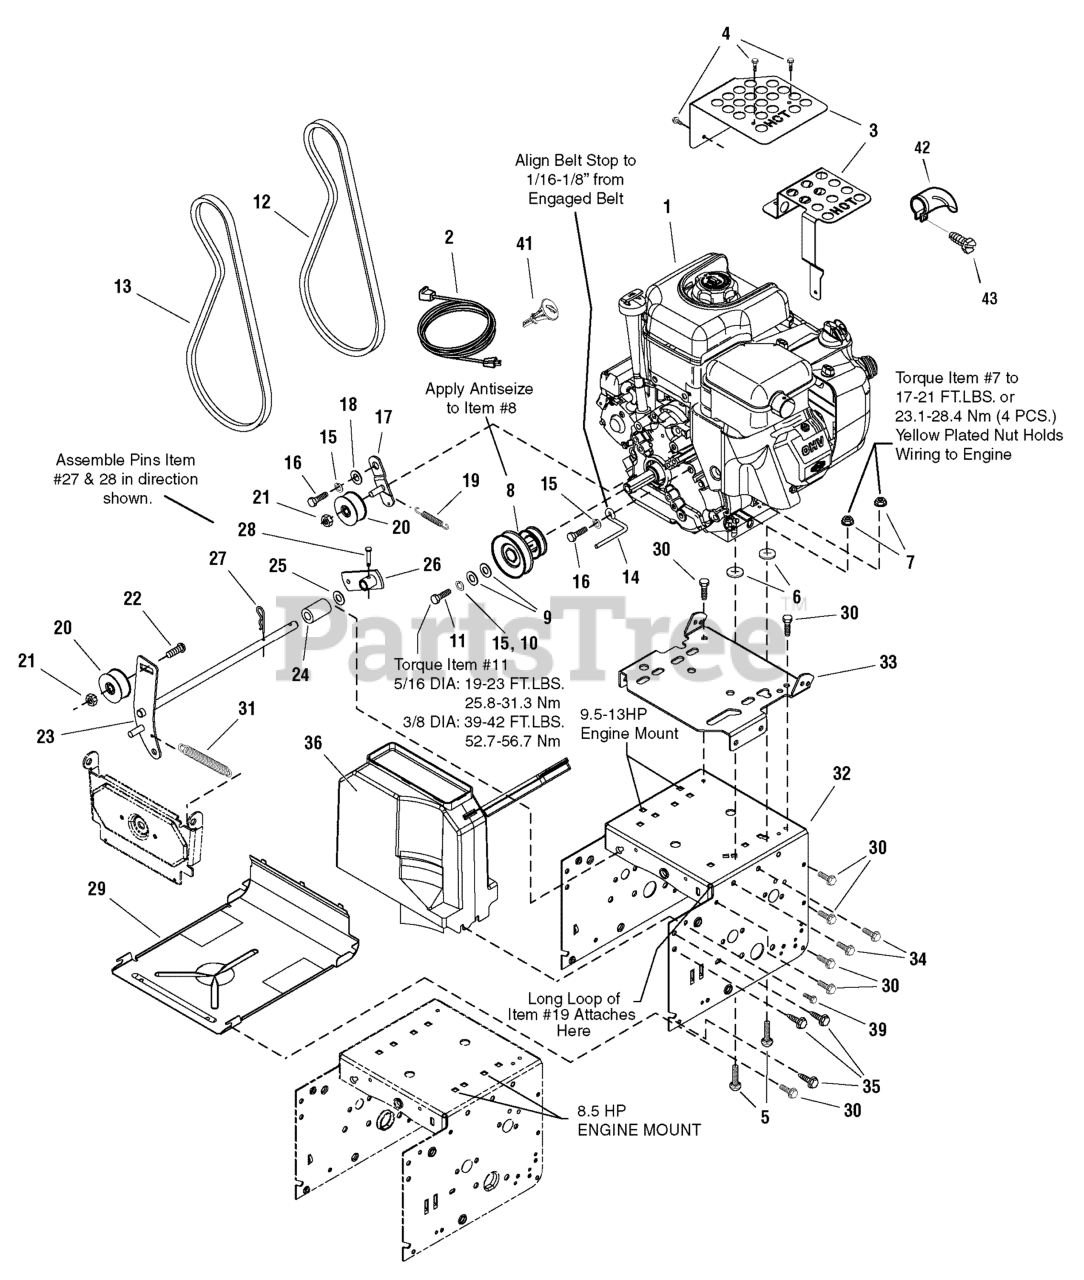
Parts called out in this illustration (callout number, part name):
1	ENGINE, 8.5HP B&S Powerbuilt *
1	ENGINE, 9.5HP B&S Powerbuilt *
2	CORD, Electric Start
3	GUARD, Muffler
4	SCREW, Hex Washer Head Taptite
5	CARRIAGE BOLT
6	NUT, Speed
7	NUT, Hex Flange, 5/16-18 Whiz Lock Small
8	PULLEY, Engine
9	WASHER, 3-5/16
9	WASHER, 3/8
10	LOCKWASHER, Spring 3/8
11	CAPSCREW, Hex Head, 5/16-24 x 1-1/4 G5
11	CAPSCREW, Hex Head, 3/8-24 x 1-1/4 G8
12	V-BELT, Drive
13	V-BELT, Auger
14	STOP, Belt
15	LOCKWASHER, Spring 5/16
16	CAPSCREW, Hex Head, 5/16-24 x 3/4 G5
17	IDLER BRACKET ASSEMBLY, Drive Belt
18	BUSHING, Idler Bracket
19	SPRING, Extension Idler
20	IDLER, Plastic Ball Bearing
21	NUT, Hex Jam, 3/8-16
22	CARRIAGE BOLT, 3/8-16 x 1-1/4
23	IDLER ASSEMBLY, Auger
24	SPACER, Auger Bracket
25	WASHER, 1/2
26	BRACKET & HUB ASSEMBLY, Spring
27	PIN, Hair
28	PIN, Clevis
29	PANEL, Bottom
30	SCREW, Hex Washer Head Taptite, 1/4-20 x 5/8
31	SPRING, Extension Auger Idler
32	FRAME BOX
33	PLATE, Engine Mount
34	SCREW, Hex Washer Head Taptite, 5/16-18 x 1/2
35	SCREW, Hex Washer Head Taptite, 5/16-18 x 3/4
36	COVER, Belt w/Toolbox Includes Decal
39	SCREW, Hex
41	KEY, Briggs Engine
42	DEFLECTOR, Muffler
